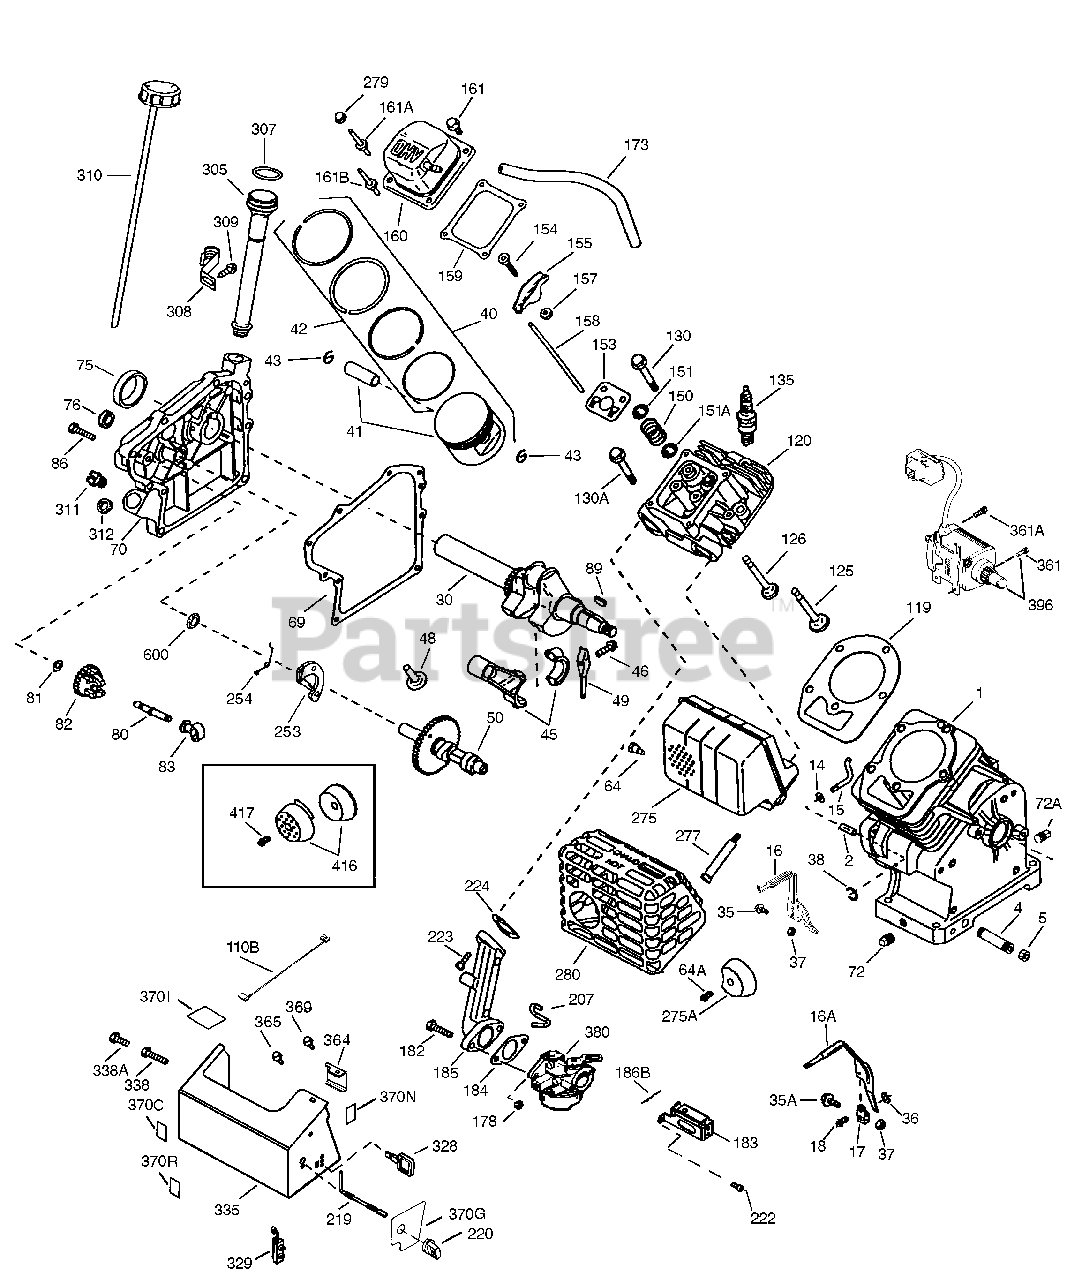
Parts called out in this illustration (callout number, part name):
1	"Cylinder (Incl. 2, 20, 72, 72A, 325 & 325A)
2	Dowel Pin
4	Oil Drain Extension
5	Extension Cap
15	Governor Rod (Incl. 38)
16	Governor Lever
25B	Air Baffle (Right)
30	Crankshaft
35	Screw, 10-32 x 63/64"
37	Lock Nut, 10-32
38	Retaining Ring
40	Piston, Pin & Ring Set (Std.)
40	Piston, Pin & Ring Set (.010" OS)
41	Piston & Pin Ass'y (Std.) (Incl. 43)
41	Piston & Pin Ass'y (.010" OS) Incl. 4 3
42	Ring Set (Std.)
42	Ring Set (.010" OS)
43	Piston Pin Retaining Ring
45	Connecting Rod Ass'y (Incl. 46 & 49)
46	Connecting Rod Bolt
48	Valve Lifter
49	Oil Dipper
50	Camshaft (Incl. 253 & 254)
66	Screw, 1/4-20 x 27/32"
69	* Cylinder Cover Gasket
70	Cylinder Cover (Incl. 75 thru 83)
75	Oil Seal
76	Camshaft Seal
80	Governor Shaft
82	Governor Gear Ass'y (Incl. 81)
83	Governor Spool
86	Screw, 1/4-20 x 1-1/4"
89	Flywheel Key (also available in Packa ged Part #740007B) also available in Packaged Part #740007B
119	* Cylinder Head Gasket
120	Cylinder Head (Incl. 151A)
125	Exhaust Valve (Std.) (Incl. 151)
125	Exhaust Valve (1/32" OS) (Incl. 151)
126	Intake Valve (Std.) (Incl. 151 & 151A )
130	Screw, 5/16-18 x 1-1/2"
130A	Screw, 5/16-18 x 2-41/64"
135	Resistor Spark Plug (RN4C) also avail able in Packaged Part #740069
150	Valve Spring
151	Valve Spring Cap
151A	Intake Valve Seal
153	Push Rod Guide
154	Rocker Arm Stud
155	Rocker Arm
157	Nut, 1/4-28
158	Push Rod
159	* Rocker Arm Cover Gasket
160	Rocker Arm Cover
173	Breather Tube
183	Choke Bracket
184	* Carburetor To Intake Pipe Gasket
185	Intake Pipe
186B	Choke Spring
207	Throttle Link
211	Screw, 10-32 x 3/8"
219	Choke Rod
220	Control Knob
222	Screw, 10-32 x 1/2"
223	Screw, 1/4-20 x 1"
224	* Intake Pipe Gasket
229	Nut, 1/4-20
229	Nut & Lock Washer
253	Compression Release Weight
254	Compression Release Spring
275	Muffler
277	Screw, 1/4-20 x 2-9/32"
280	Heat Shield
305	Oil Fill Tube
307	"O" Ring
308	Oil Fill Tube Clip
310	Dipstick
328	Ignition Key (also available in Packa ged Part #740077) also available in P ackaged Part #740077
335	Carburetor Cover
338	Screw, 10-32 x 1/2"
361	Screw, T-30, 1/4-20 x 15/32" (Electri c Starter Mounting Screws)
364	Carburetor Cover Bracket
370	Decal - Primer - International Symbol
370	-1
370	Decal - Speed Control - ChokeKey
370	Warning Decal (Bilingual)
380	Carburetor (Incl. 184)
396	Electric Starter Motor
416	Spark Arrestor Kit (Incl. 417) Option al
701	Screw, 1/4-20 x 31/64"
900	Replacement Short Block, order from 7 1-999Replacement Engine, None
999	Winter Maintenance Kit incl. 5W30 Oil , Spark Plug, Key & Ultra-Fresh
999	Winter Maintenance Kit (incl. 0W30 Sy nthetic Oil, Spark Plug, Key & Ultra- Fresh)
